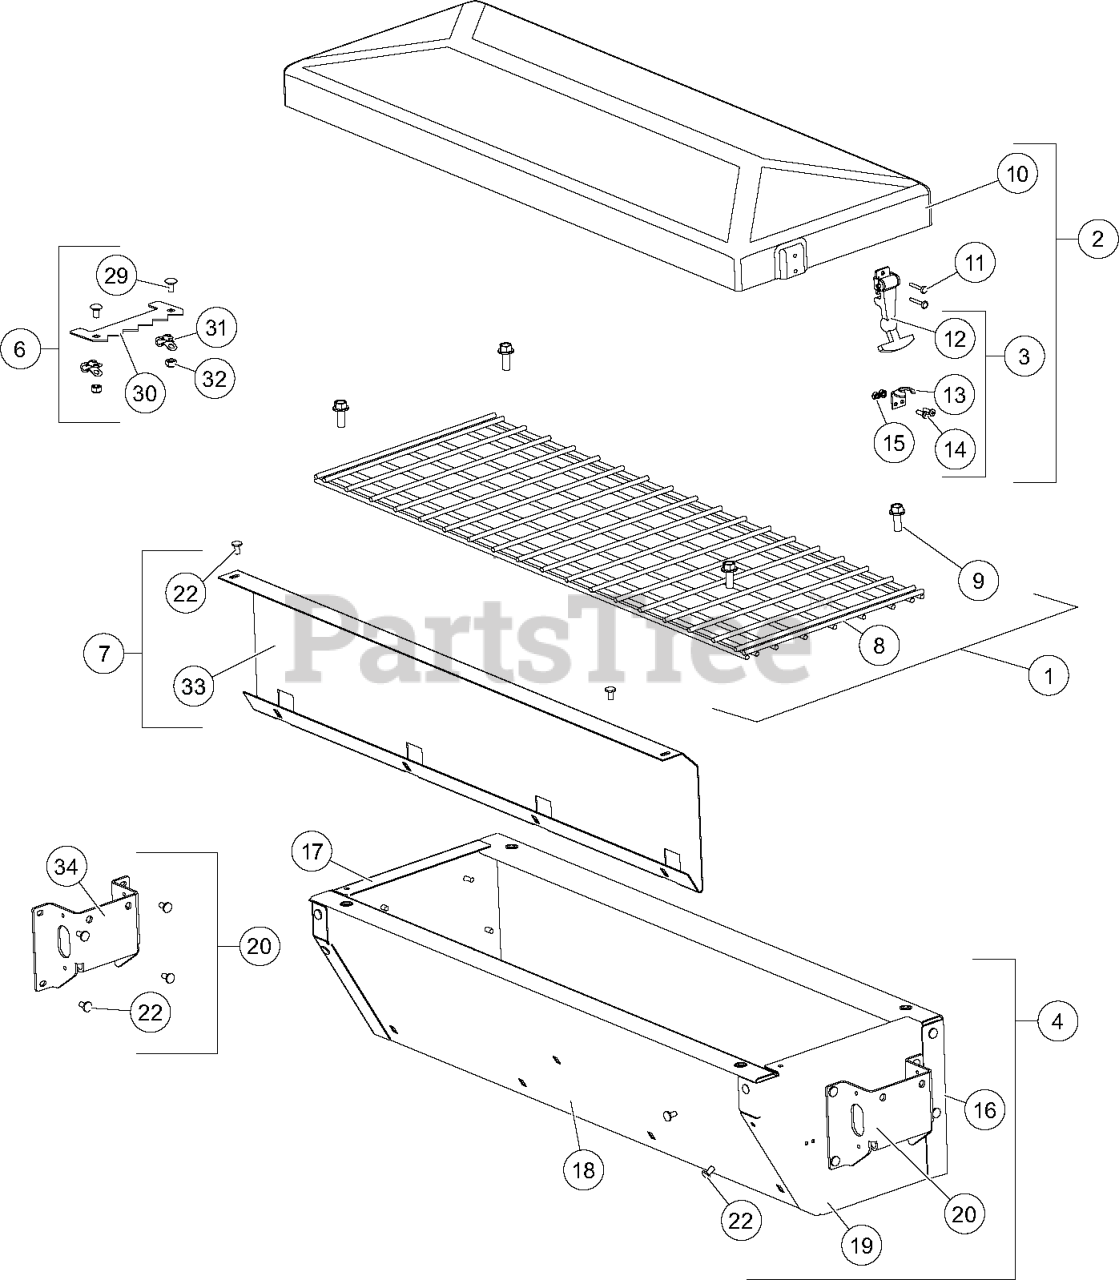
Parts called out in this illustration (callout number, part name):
1	TOP SCREEN KIT, 250
2	LID KIT, 250
3	LATCH KIT
4	HOPPER KIT, 250
6	BAG SPLITTER KIT
7	BAFFLE KIT
8	TOP SCREEN
9	3/8-16 X 1 HEX CAP SCREW SS
10	LID
11	3/16 POP RIVET
12	LATCH
13	KEEPER
14	#10-32 X 5/8 MACHINE SCREW SS
15	#10-32 HEX LOCKNUT SS
16	REAR SIDE, 2.5 CU FEET
17	END CAP, 2.5 CU FT - PS
18	FRONT SIDE, 2.5 CU FEET
19	END CAP, 2.5 CU FEET - DS
20	HANDLE KIT
22	1/4 RIVET SS
29	1/4-20 X 1/2 CARRIAGE BOLT SS
30	BAG SPLITTER
31	CLAMP, 5/16 RUBBER COATED
32	1/4-20 HEX LOCKNUT GB
33	BAFFLE
34	HANDLE
